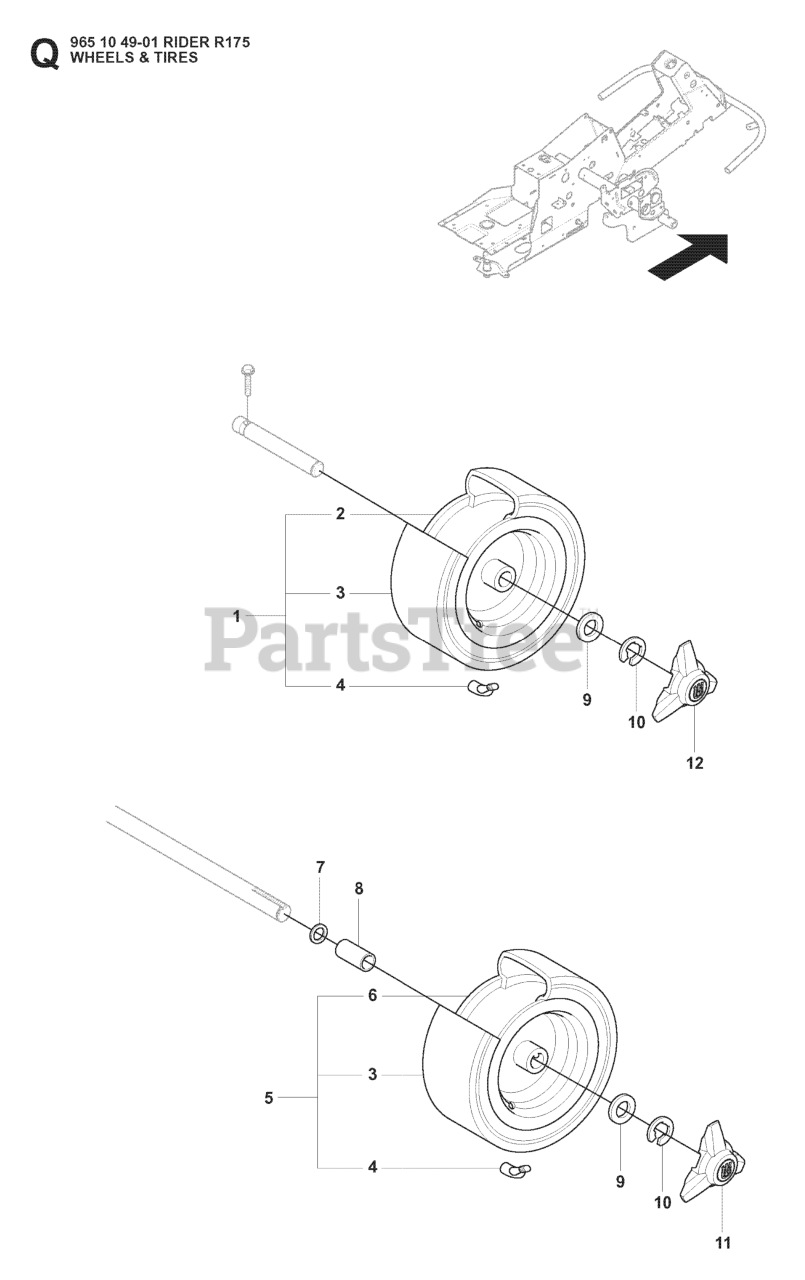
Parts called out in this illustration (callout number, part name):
5	WHEEL
6	RP RIM
10	SPACE SLEEVE
12	RETAINING RING
